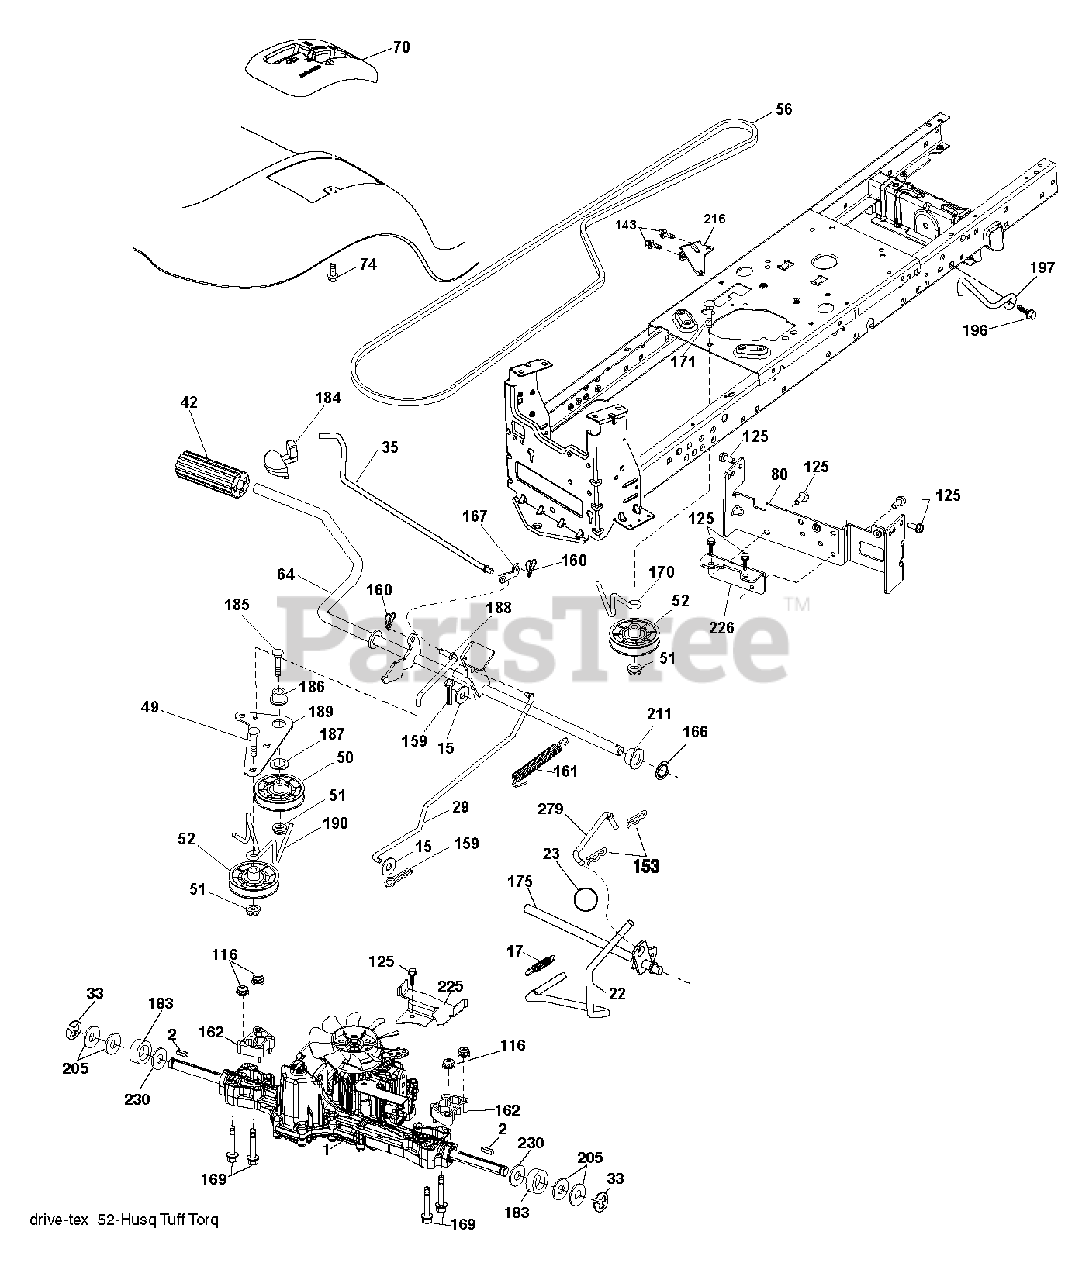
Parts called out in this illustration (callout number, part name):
2	SQUARE KEY
17	SPRING.BRAKE.K46.GREEN
22	SHIFTER ROD
23	PISTOL KNOB
29	ROD.BRAKE.K46
33	E-RING LT
35	ROD.BRKAE.PARKING.STEALTH
42	PEDAL COVER T
49	BOLT
50	IDLER.FLAT.910.OFFSET
51	NUT LOCK FLG 3/8-16 UNC
52	IDLER.V-GROOVE.910.OFFSET
64	SHAFT.ASM.PEDAL.BRAKE.
74	SCREW.HI-LO.CONSOLE
80	STRAP.TORQUE.HG3000/K46
116	NUT LOCK HEX FLANGE 5/16-18
125	SCREW
153	RETAINER M
159	COTTER PIN
160	RETAINER CLIP
161	SPRING.RETURN.CLUTCH.2006
162	SPACER.TRANSAXLE.18&22
166	NUT.PUSH.625
167	LATCH.BRAKE.SPRING
169	BOLT.HEX.FLNG.5/16-18X3.75
170	KEEPER.V-IDLER.CENTER.
171	BOLT
175	SHAFT ASM SHIFT
183	SPACER AXLE
184	HANDLE.PRKG.BRAKE.STLTH.TX.RED
186	SPACER.RETAINER
187	WASHER 12/32X2X10GA
188	LINK.CLUTCH.GROUND.DRIVE
189	BELLCRANK.GROUND.DRIVE.TEX.
190	KEEPER.BELLCRANK.DRIVE
196	SCREW 3/8-16X1
197	LINK.CLUTCH.ANIT-ROTAT
211	BEARING.NYLON
216	BRACKET.PULLEY.IDLER.W/TEX
225	KEEPER.BELT.TRANSAXLE.K46
226	BRKT.MOUNT.TORQUE.K46.
230	WASHER.HARDENED
279	LINK SHIFT
